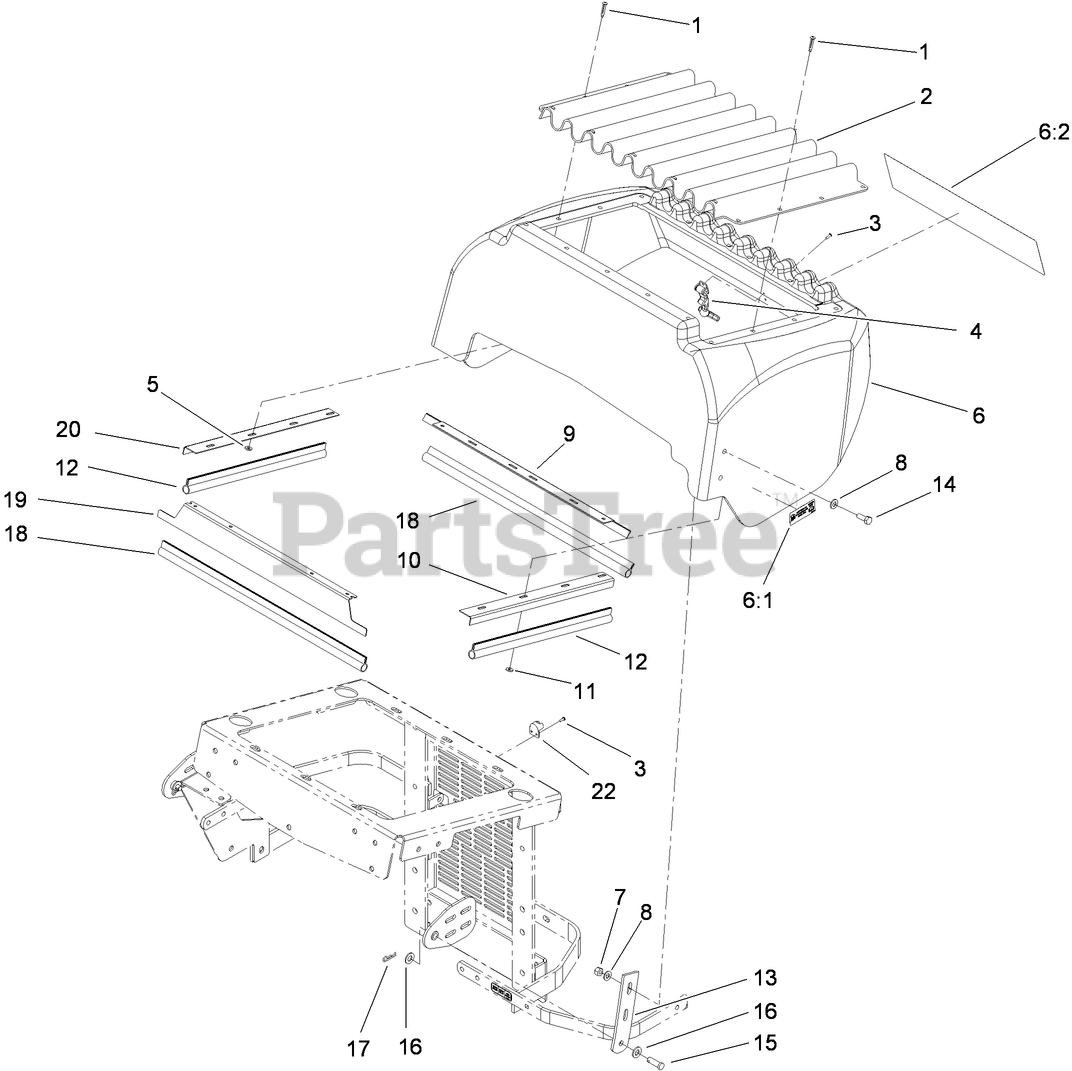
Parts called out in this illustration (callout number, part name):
2	SCREEN-RADIATOR
3	RIVET
4	LATCH-RUBBER
5	WASHER-SPRING
6	HOOD ASM
6:1	DECAL-LOW SULFUR
7	NUT-LOCK, NI
8	WASHER-PLAIN
9	ANGLE-RADIATOR, BOTTOM
10	ANGLE-RADIATOR, LH
11	WASHER-FLAT
12	SEAL-TRIM
13	PLATE-HINGE, HOOD
14	SCREW-HH
15	PIN-CLEVIS
16	WASHER-FLAT
17	PIN-COTTER
18	SEAL-TRIM
19	BRACKET SEAL, RADIATOR FRONT
20	ANGLE-RADIATOR, RH
22	KEEPER-LATCH, RUBBER
